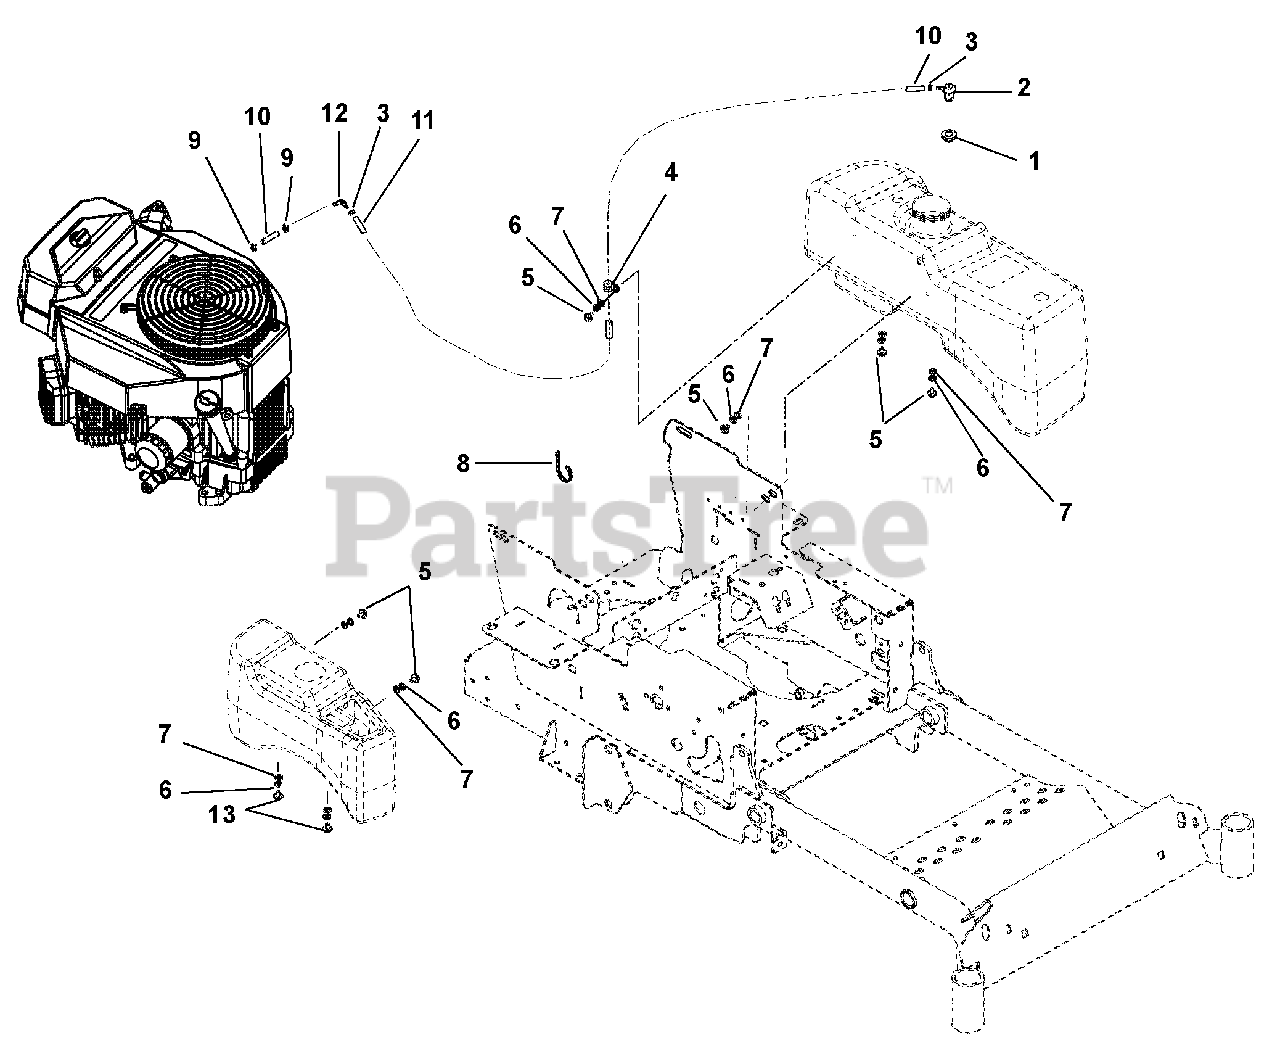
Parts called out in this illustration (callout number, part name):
1	GROMMET, REMOTE VENT NITRILE
2	VALVE, COMBINATION
3	CLAMP, FUEL LINE
4	CLAMP, CUSHIONED STEEL
5	BOLT-HEX.31-18X.875 YWZC GR5
6	@WSHR-LK .31X.078 REG YWZC
7	@WSHR-FL-STL.38X.875X.083 YWZC
8	CABLE TIE LG 5-1/2
9	CLAMP-HOSE, SPRING .188
10	HOSE, .188 LOW-PERM BULK GAS
11	HOSE, .25 LOW-PERM BULK GAS
12	FITTING-3/16X1/4 90DEGREE VAC
13	SCR-PLASTITE .25-10X.75, YWZC
